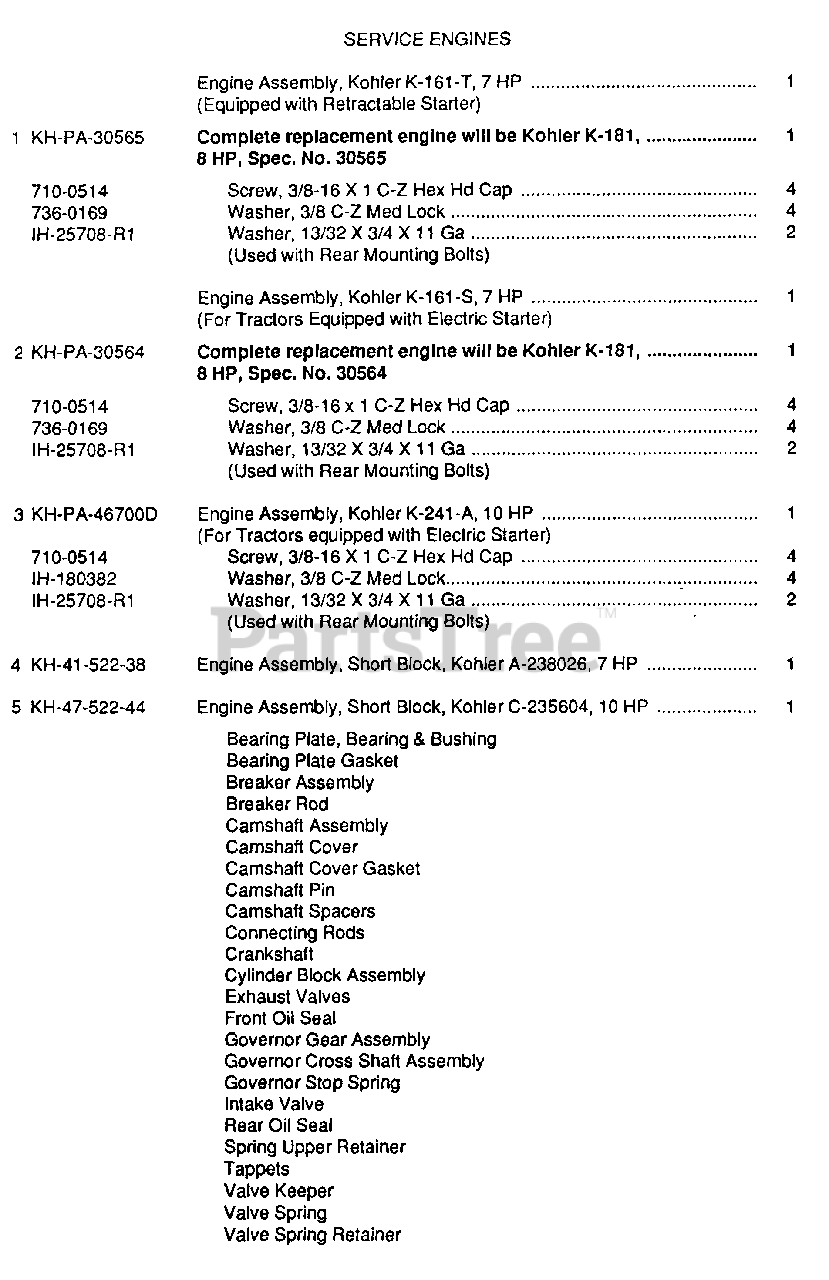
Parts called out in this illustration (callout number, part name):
2	Complete replacement engine will be Kohler K-181, 8 HP, Spec. No 30564
3	Engine Assembly, Kohler K-241-A, 10 HP
4	Engine Assembly, Short Block, Kohler A-238026, 7 HP
5	Engine Assembly, Short Block, Kohler C-235604, 10 HP
